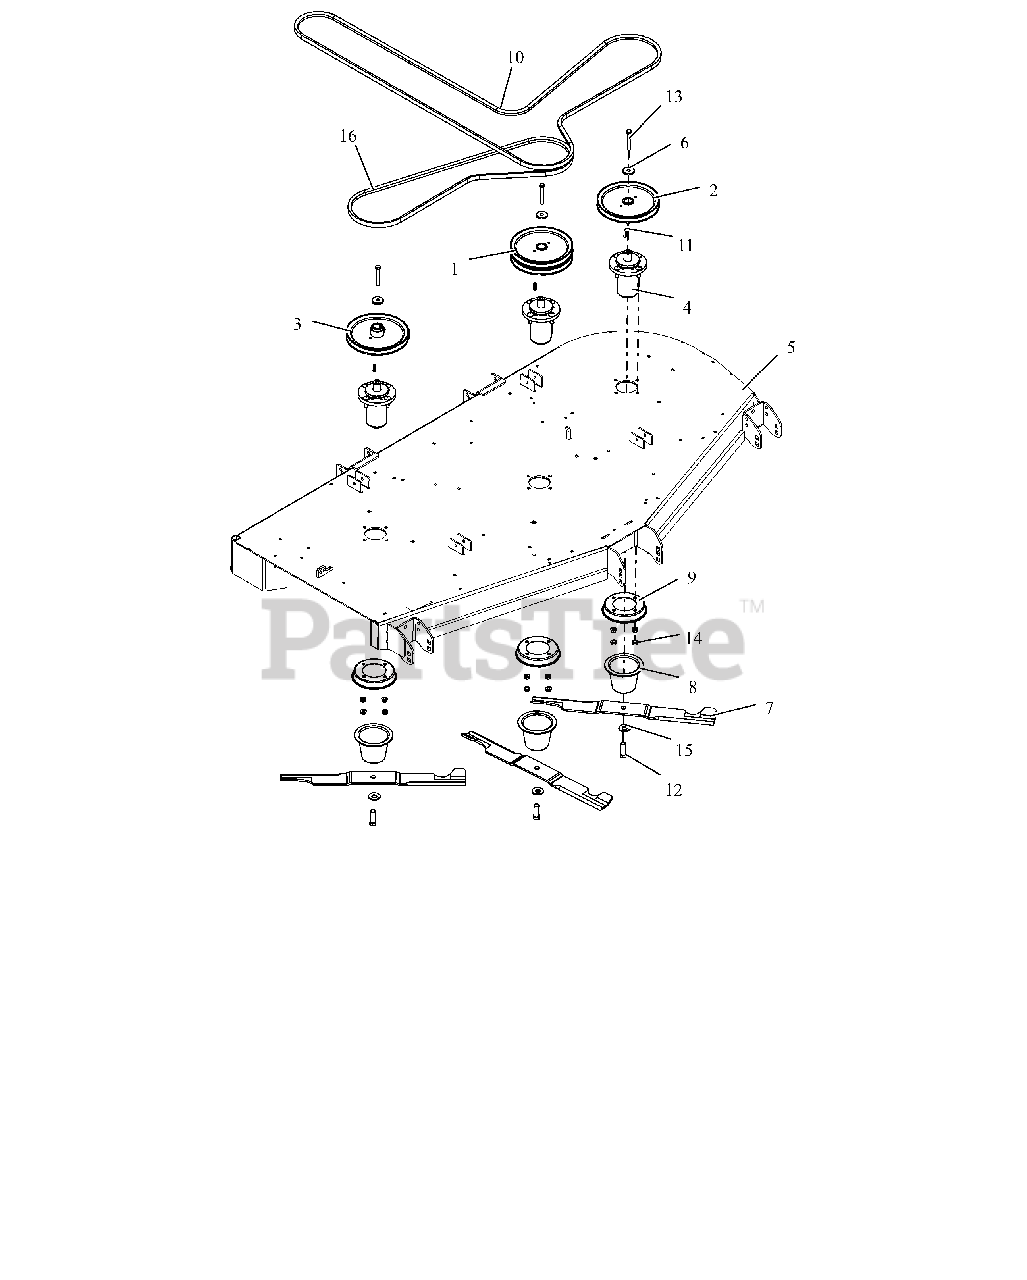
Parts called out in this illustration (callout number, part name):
1	SHEAVE-DOUBLE 1.00"IDX8.25"OD
2	SHEAVE-SINGLE 1.00"IDX8.25"OD
3	SHV-SINGLE 1.00"ID X 8.25"OD
4	ASM, MAINT FREE ALUM SPINDLE
5	72"SIDE DISCH DECK WMT W/SAFE
6	RETAINER, SHEAVE
7	BLADE, 72"
8	GUARD, SPINDLE LOWER
9	GUARD, SPINDLE TOP
10	V-BELT, HB WRAPPED
11	KEY, SQ .25X.25X1.00 RC 40-50
12	BLT, HEX .62-18X1.75 G8 ZCC
13	BLT, HEX .38-16X2.75 G8 ZCC
14	NUT-LK-CTR-FLG .375-16 GF ZCC
15	WSHR-BLVL .669X1.535X.138
16	V-BELT, B-COGGED
